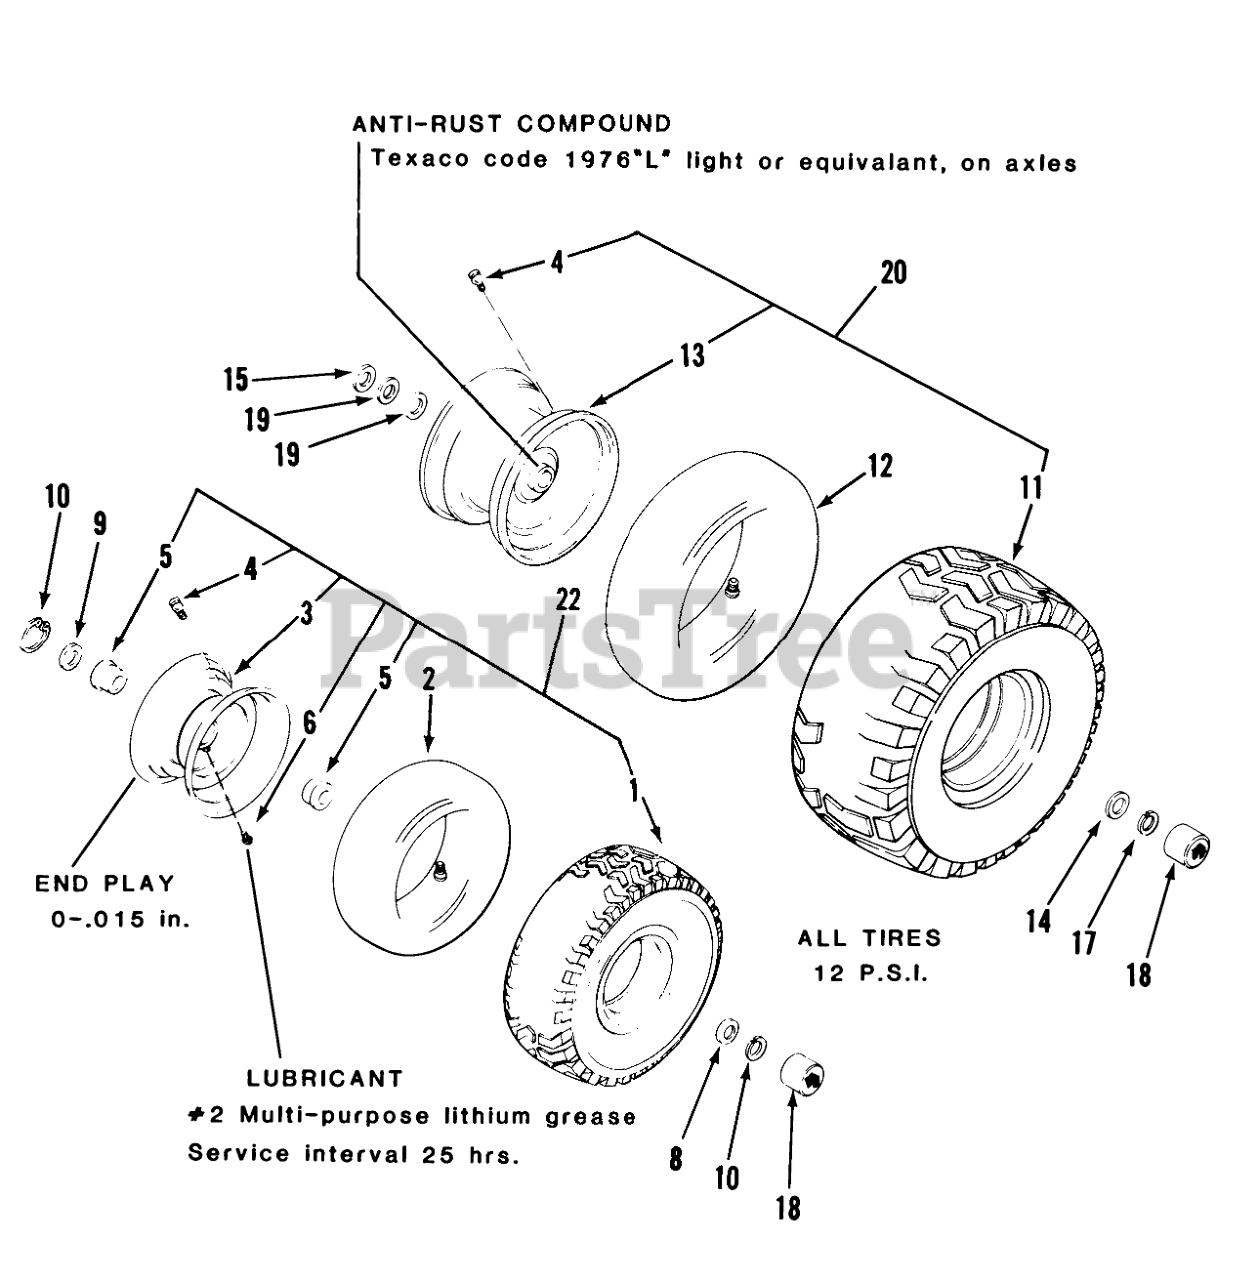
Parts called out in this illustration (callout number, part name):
1	TIRE
2	Front Tube-Service Only
3	Wheel-Front (Includes Item Numbers 4, 5, 6)
4	VALVE
5	FLANGE BEARING
6	Zerk
8	WASHER-FLAT
9	WASHER-SHIM
9	WASHER
10	Snap Ring
11	TIRE15 X 6.00-6
13	ASSY-RIM
14	WASHER-FLAT
15	WASHER
17	Snap Ring
18	HUB CAP
19	WASHER-SHIM
20	Rear Wheel and Tire Assy
22	Front Wheel and Tire Assy
